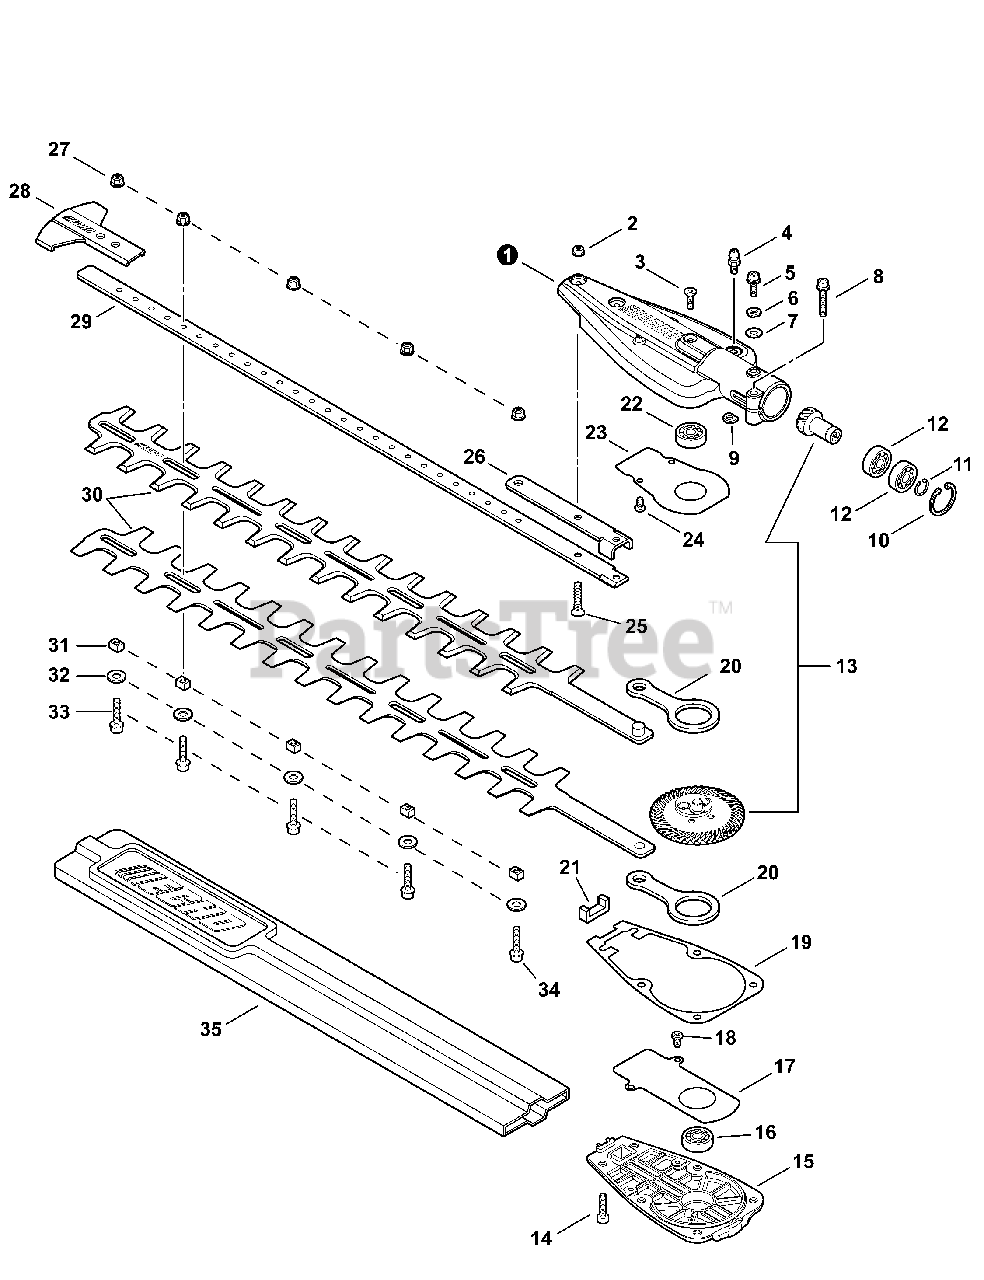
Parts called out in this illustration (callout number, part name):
1	CASE, GEAR
2	NUT - FLANGE
3	SCREW - 5×8
4	FITTING, GREASE
5	SCREW - 5×12
6	WASHER, SPRING 5
7	WASHER, FLAT 5.5×10×0.8
8	SCREW - 5×25
9	WASHER, SHIM
10	RING, RETAINING - 24
11	RING, RETAINING - 12
12	BEARING, BALL - 6901
13	GEAR SET
14	SCREW - 5×12
15	LID, GEAR CASE
16	BEARING, BALL - 628ZZ
17	GASKET, GEAR CASE
18	SCREW - 4×5
19	PLATE, WEAR
20	ROD, CONNECTING
22	BEARING, BALL - 608ZZ
23	PLATE, WEAR
24	SCREW - 4×5
25	SCREW - 5×18
26	SUPPORT, BLADE
27	LOCKNUT - 5
28	GUARD, TIP
29	SUPPORT, BLADE
30	BLADE, TRIMMER
31	GUIDE, BLADE
32	WASHER - 6
33	SCREW - 5×20
34	SCREW - 5×22
35	COVER, BLADE
